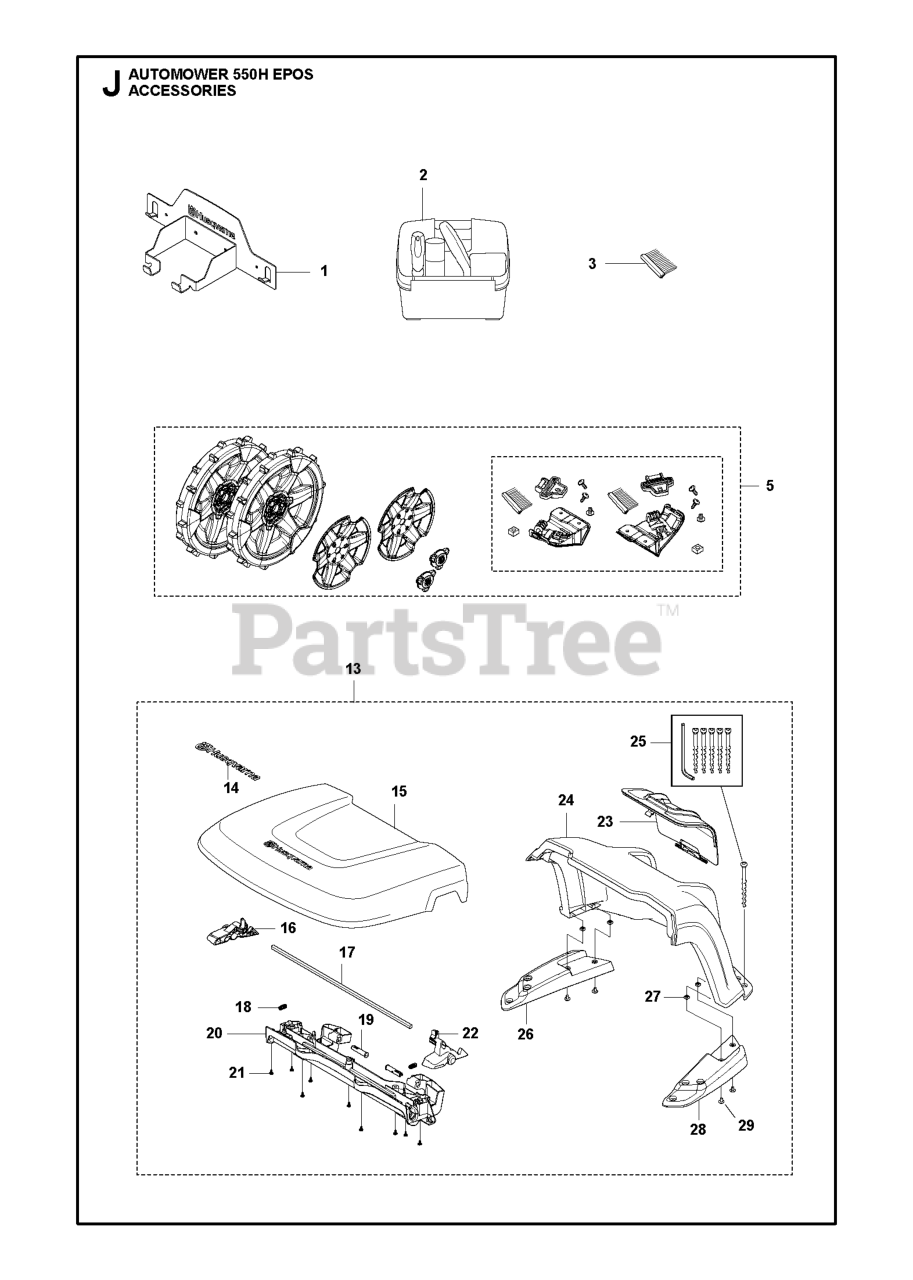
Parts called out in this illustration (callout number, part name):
1	HANGER
2	CLG
5	AUTOMOWER ACCY
13	COVER
14	DECAL
16	HANDLE RELEASE LEFT
17	ROD
18	SPRING SPRING CAP
19	HINGE PIN
20	BEAM
21	SCREW 14MM
22	HANDLE RELEASE RIGHT
23	HATCH
25	Screws
26	SUPPORT BASE LEFT
27	NUT
28	SUPPORT BASE RIGHT
29	SCREW IHPANM M6X25 4.6 ZP-BC
